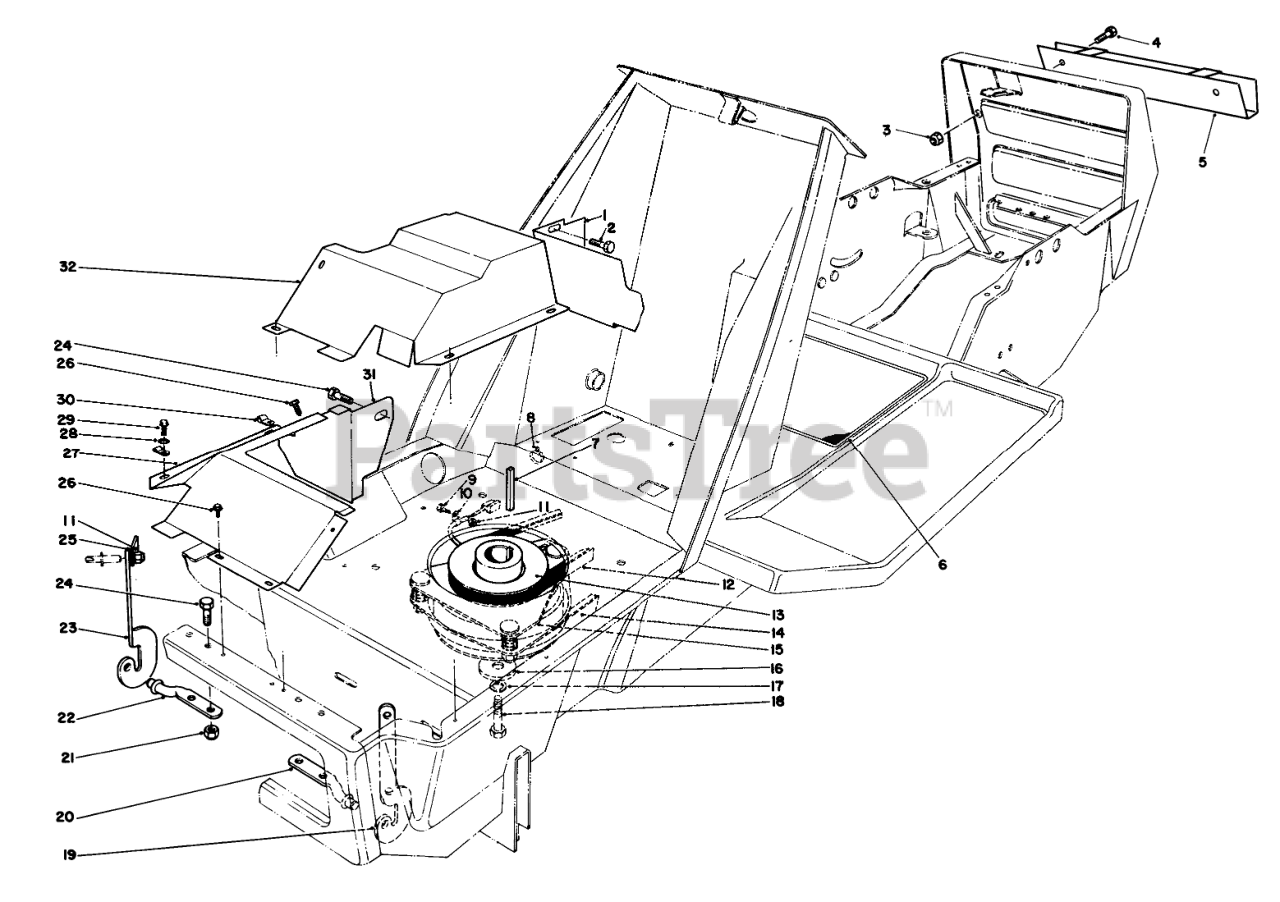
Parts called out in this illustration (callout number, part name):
1	EXH SHIELD SUPT B
2	SCREW-HH
3	NUT-LOCK, NI
4	SCREW-HH
5	ADAPTER CHANNEL WA B
6	OPERATION DECAL
7	KEY-SQUARE
8	TIE-MOUNT, PUSH
9	SCREW-HH
10	CLAMP
11	NUT-LOCK, NI
12	V BELT
13	Pulley
14	V-BELT
15	Clutch Assembly-Deck
16	WASHER-CLUTCH
17	WASHER-LOCK
18	SCREW-HH
19	L.H. HINGE BRACKET
20	LH HOOD HINGE PIN
21	NUT-LOCK, CONE
22	RH HOOD HINGE PIN
23	RH HINGE BRKT
24	SCREW-HH
25	SCREEN SUPT BRKT
26	SCREW-HWHTF
27	Heat Shield
28	WASHER-FLAT
29	SCREW
30	CABLE CLAMP
31	Support Heat Shield
32	HEAT SHIELD WA B
